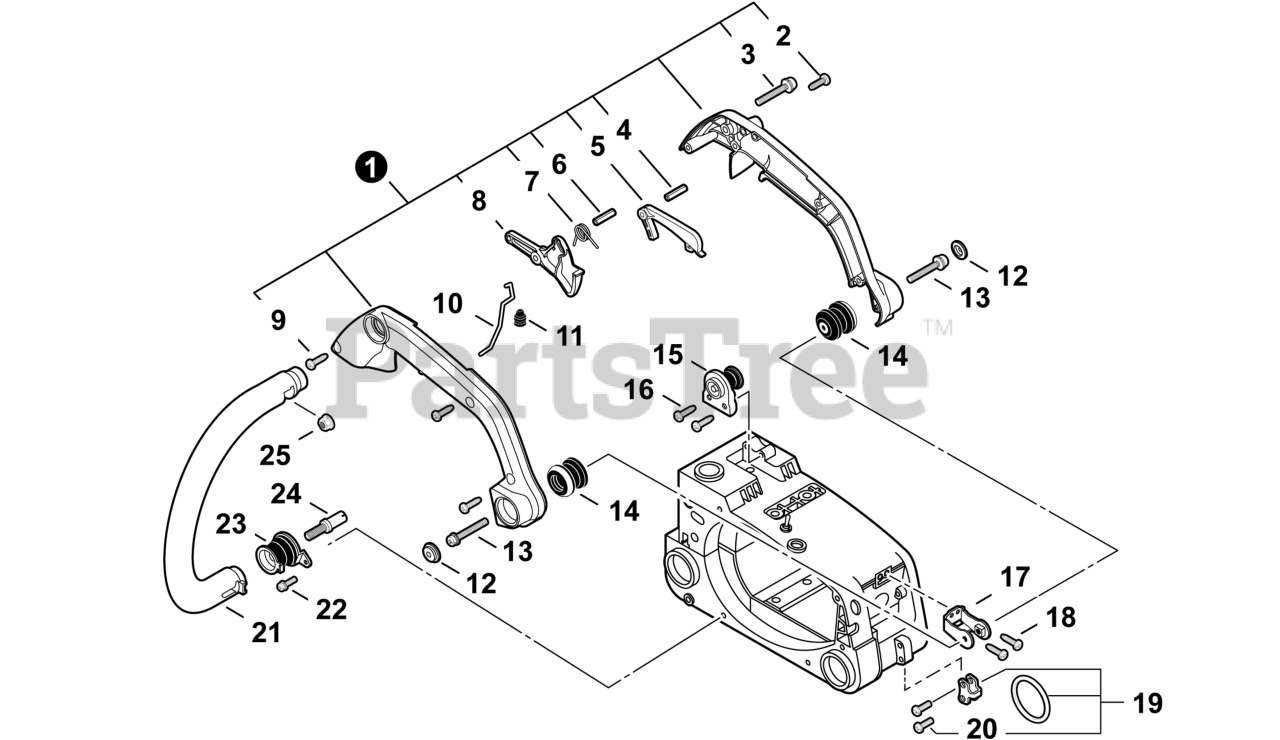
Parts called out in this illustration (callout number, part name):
1	HANDLE SET, REAR
2	SCREW 5×14
3	SCREW 5×35
4	PIN, SPRING 4×20
5	LOCKOUT, THROTTLE
6	PIN, SPRING 4×25 SUS
7	SPRING, TORSION
8	TRIGGER, THROTTLE
9	SCREW 4×16
10	ROD, THROTTLE
11	GROMMET, THROTTLE ROD
12	CAP, CUSHION
13	SCREW 4×10
14	CUSHION 4
15	CUSHION 5
16	SCREW 4×14
17	BRACKET, HANDLE
18	SCREW 4×14
19	HANGER SET, HARNESS
20	SCREW 4×16
21	HANDLE, FRONT
22	SCREW 4×16
23	CUSHION 5
25	NUT, FLANGE M5
